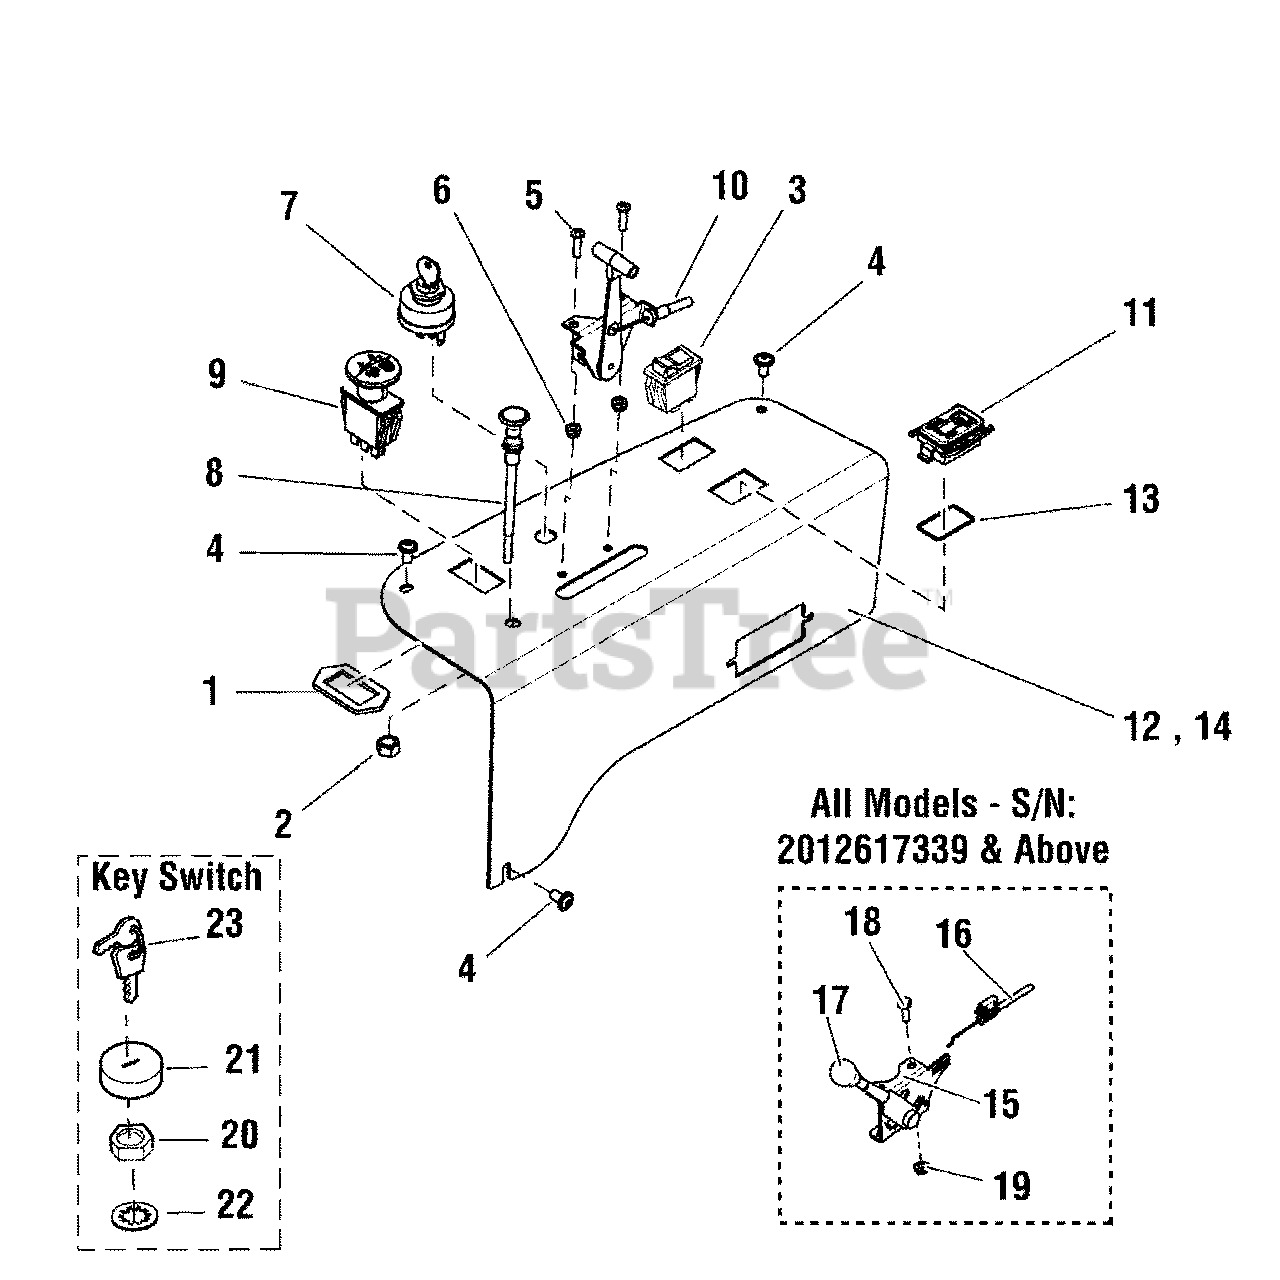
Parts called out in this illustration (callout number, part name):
1	SWITCH RETAINER RING
2	NUT, 3/8-24 Hex
3	SWITCH, LIGHT
4	SCREW, Allen Head, 1/4-20 x 1/2
5	BOLT,1/4-20X5/8
6	NUT, 1/4-20 Hex Nylon Lock
7	SWITCH ASMY-IGNITION INDAK NO KEYS/ HDWR
8	CABLE, Choke Control, 47"
9	SWITCH, PTO
10	CABLE, Throttle Control, 40"
11	HOURMETER, Digital
12	CONTROL PANEL
13	O-RING, 7/8" ID X 1/16" W
14	PLATE, CONTROL PANEL - BLACK
15	LEVER, THROTTLE CONTROL
16	CABLE, THROTTLE, 42"
17	KNOB, THROTTLE CONTROL (SV)
18	SCREW, #10-24 X 3/4" ROUND PHILLIPS
19	NUT, #10-24 HEX NYLON LOCK
20	NUT-HEX FLANGE, 5/8-32 IGN SW DIE CAST
21	COVER, SWITCH
22	LOCKWASHER-INTERNAL TOOTH .625 THIN BLK
23	KEYS, BLISTER PK KIDS+MWRS DON'T MIX, DOM
